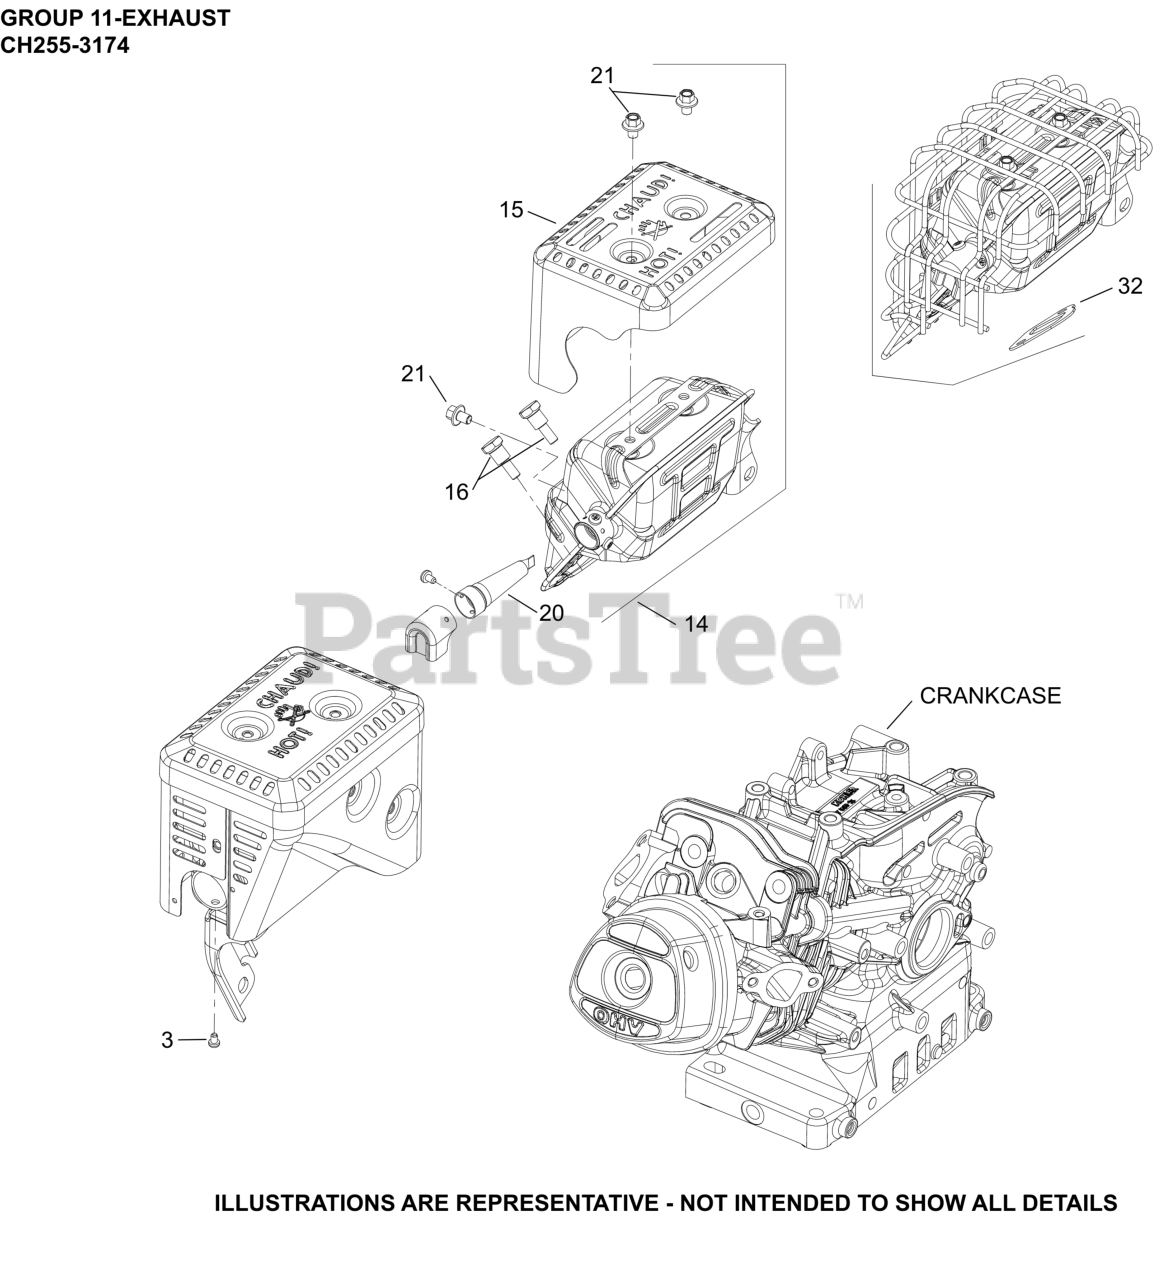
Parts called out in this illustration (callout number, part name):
3	SCREW, SPARK ARRESTOR
14	MUFFLER, ASSEMBLY
15	KIT, MUFFLER GUARD
16	SCREW, SHOULDER
20	SPARK ARRESTOR, ASSEMBLY
21	SCREW, M6 X 8 HEX FLANGE HEAD
32	GASKET, MUFFLER
